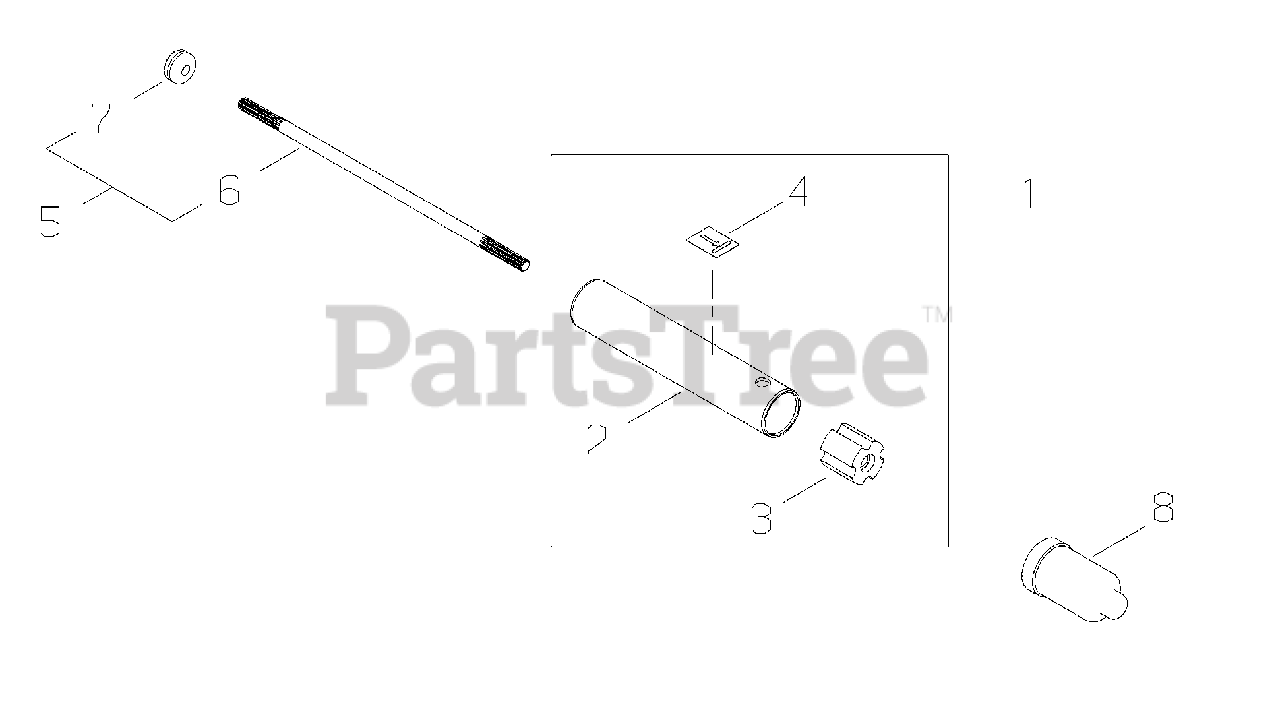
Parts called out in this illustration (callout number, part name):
1	MAIN PIPE ASSY
2	PIPE - OUTER
3	BUSHING
4	LABEL - ALIGNMENT
5	MAIN PIPE ASSY
6	PIPE, MAIN
7	GROMMET
8	CAP
